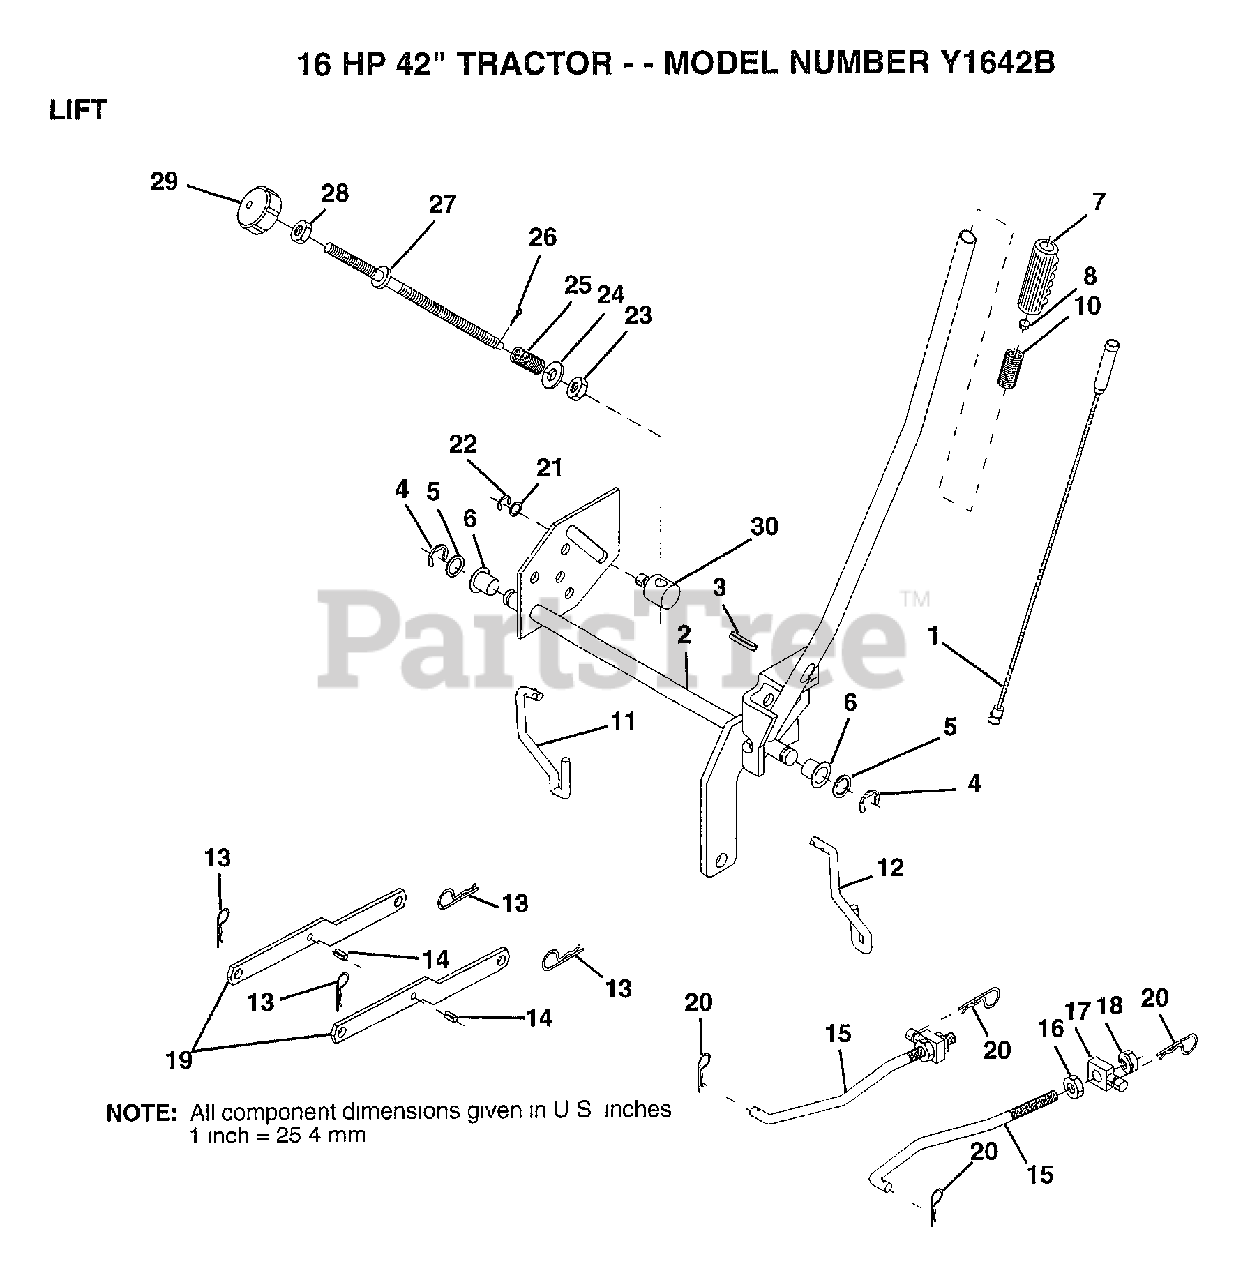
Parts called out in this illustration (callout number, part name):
1	WIRE.ASM.INNER
2	SHAFT.ASM.LIFT.RH
3	PIN GROOVE
5	WASHER
6	NYLON BEARING
7	GRIP
11	LINK LIFT LH
12	LIFT LINK RH
14	"PIN,SPRING"
15	LINK.FRONT
16	NUT
17	TRUNION
18	NUT.LK.W/WSH.1/2.
20	RETAINER.SPRING
21	WASHER
22	KLIP RING
23	NUT T
24	WASHER
25	SPRING T
27	ROD LIFT LT
28	NUT
29	KNOB INF 3/8-16
30	TRUNION LT
